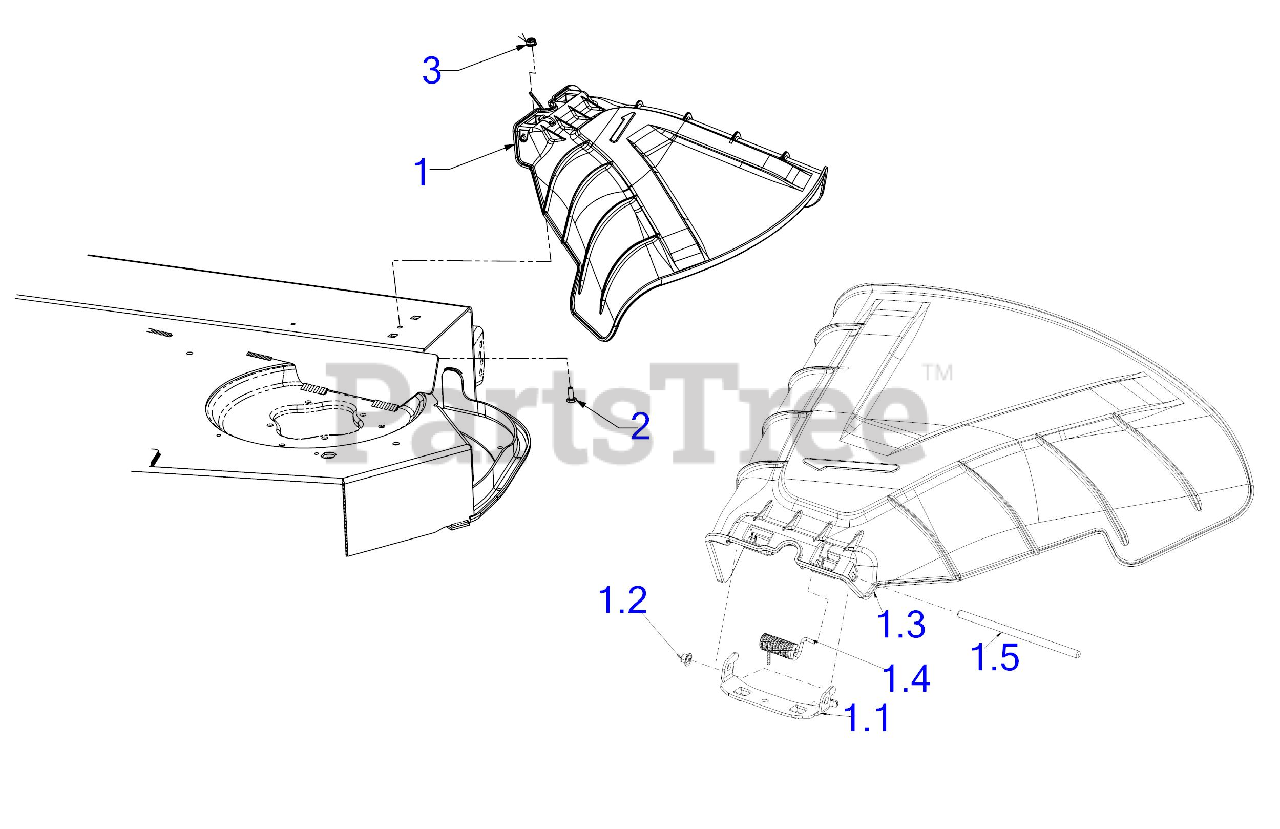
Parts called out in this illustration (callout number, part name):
1	CHUTE ASSEMBLY
1.1	CHUTE MOUNTING BRACKET
1.3	CHUTE (Order Assembly)
1.4	TORSION SPRING
1.5	CHUTE HINGE PIN
2	SCREW 1/4-20 x .620 GR5
3	FLANGE LOCK NUT
